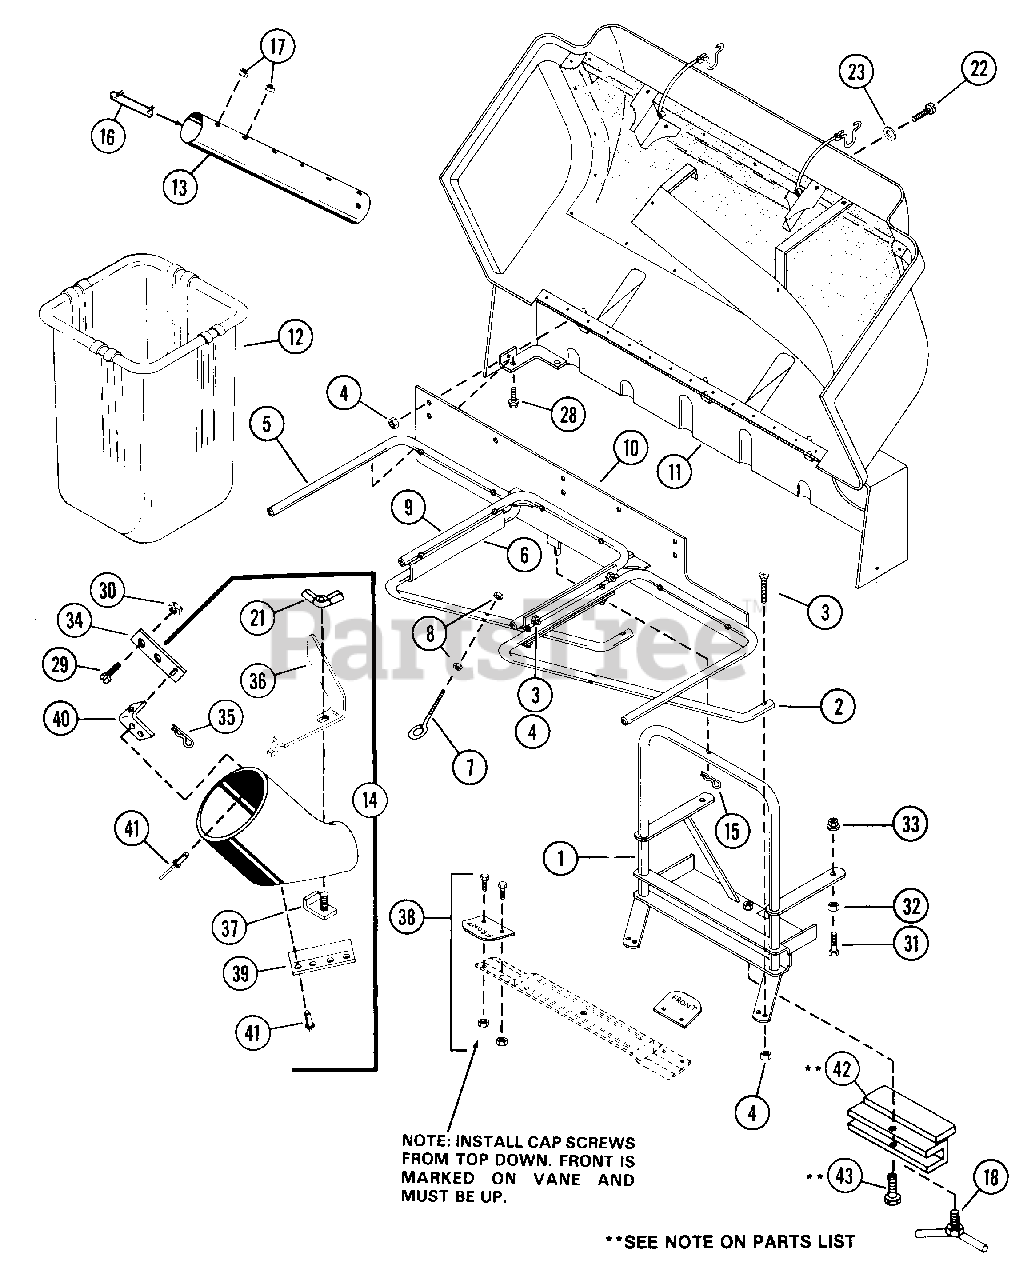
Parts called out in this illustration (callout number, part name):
1	ATTACHMENT FRAME
2	RIGHT TUBE
3	SCREW, MACHINE 5/16-18X1.50
4	NUT, LOCK 5/16-18
5	LEFT TUBE
6	TUBE BRACKET
7	EYEBOLT
8	NUT, LOCK 1/4-20
9	CENTER TUBE
10	MOUNTING BRACKET
11	COVER ASSEMBLY
12	GRASS BAGGER BASKET
13	TUBE BLANK
14	BOOT ASSEMBLY-38"
15	HAIR PIN, INTERNAL
16	CLIP
17	NUT, LOCK 1/4-20 FLANGE
18	T-HANDLE BOLT
21	NUT, WING 5/16-18
22	SCREW, MACHINE 5/16-18X.75 T/HD
23	WASHER, .339/.359X1.125X.063 PL
28	BOLT, HEX 5/16-18X.50
29	SCREW, MACHINE 10-24X.375 P/HD
30	NUT, LOCK 10-24
31	BOLT, HEX 3/8-16X1.25
32	NUT, HEX 3/8-16
33	NUT, LOCK 3/8-16
34	STRAP
35	PIN, HAIR INTERNAL .094X1.875
36	BOOT STRAP
37	CLIP CONE
38	VANE ASSEMBLY
39	EXTENSION CHUTE
40	RETAINER
41	RIVET OVAL .187X.375
42	ADAPTOR
43	BOLT, HEX 1/2-13X2.25
